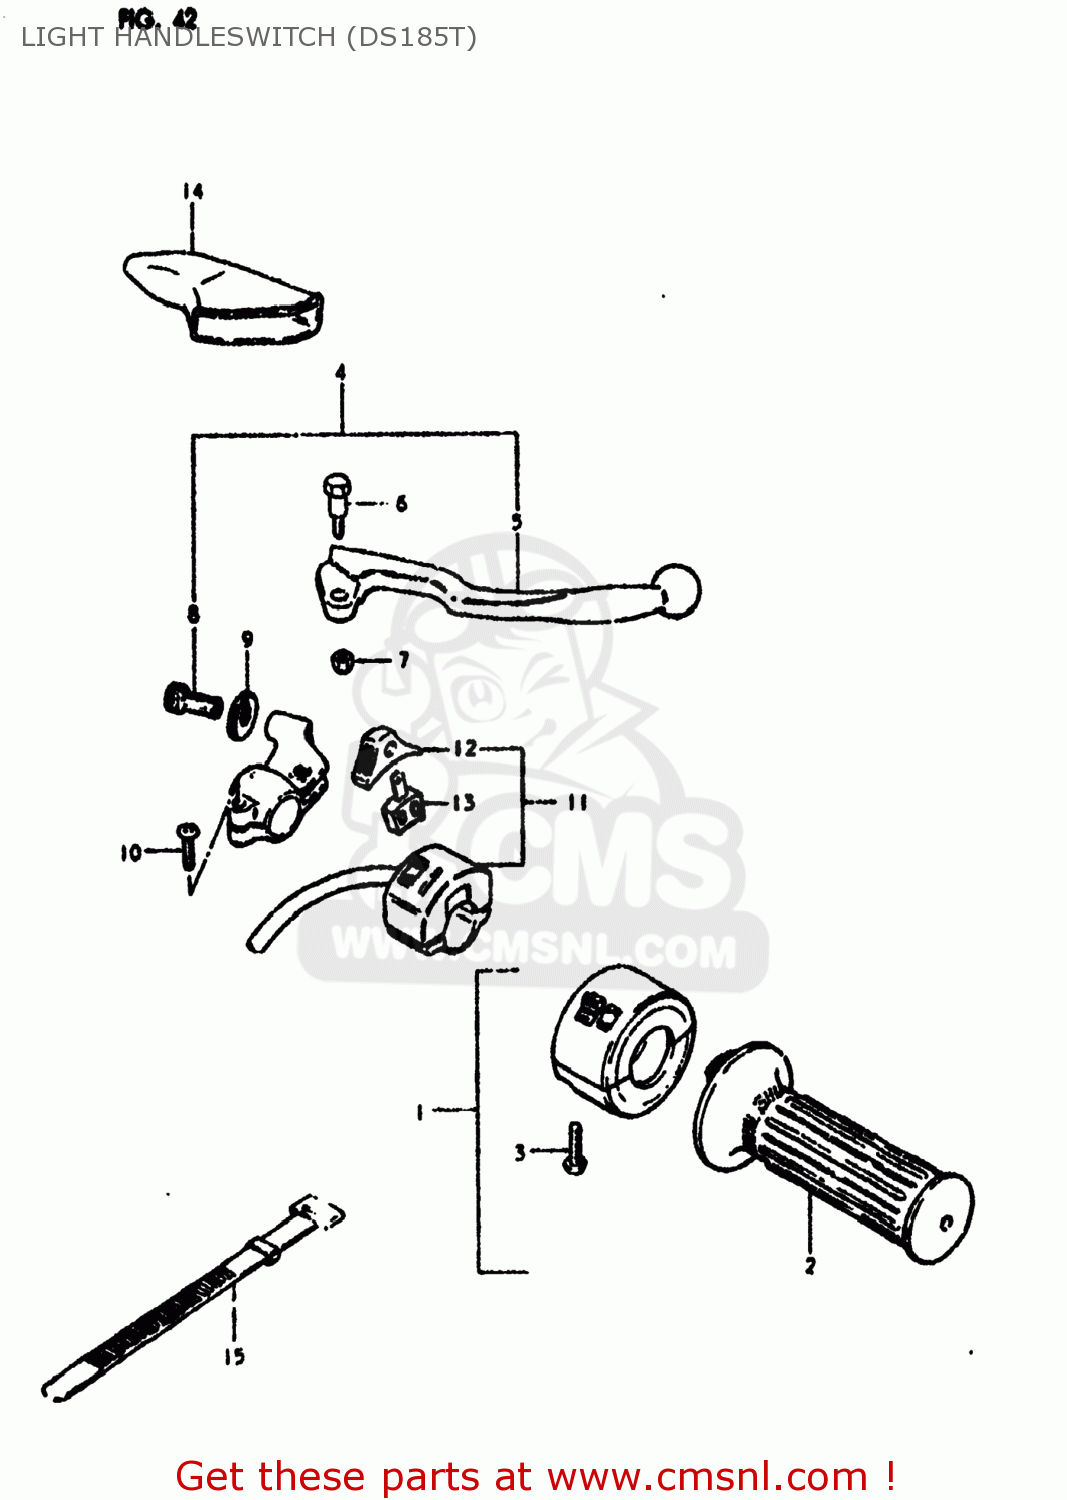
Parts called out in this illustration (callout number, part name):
1	CASE ASSEMBLY,THROTTLE
2	GRIP,THROTTLE
3	SCREW
4	LEVER ASSEMBLY,BRAKE
5	LEVER,BRAKE
6	BOLT,LEVER
7	NUT 6MM
8	ADJUSTER,CABLE
9	NUT,CABLE ADJUSTER
10	SCREW
11	SWITCH ASSEMBLY,LIGHTING
12	KNOB,LIGHTING & DIMMER
13	BLOCK,LIGHTING/DIMMER
14	COVER,CLUTCH LEVER
15	CLAMP(L:120)
